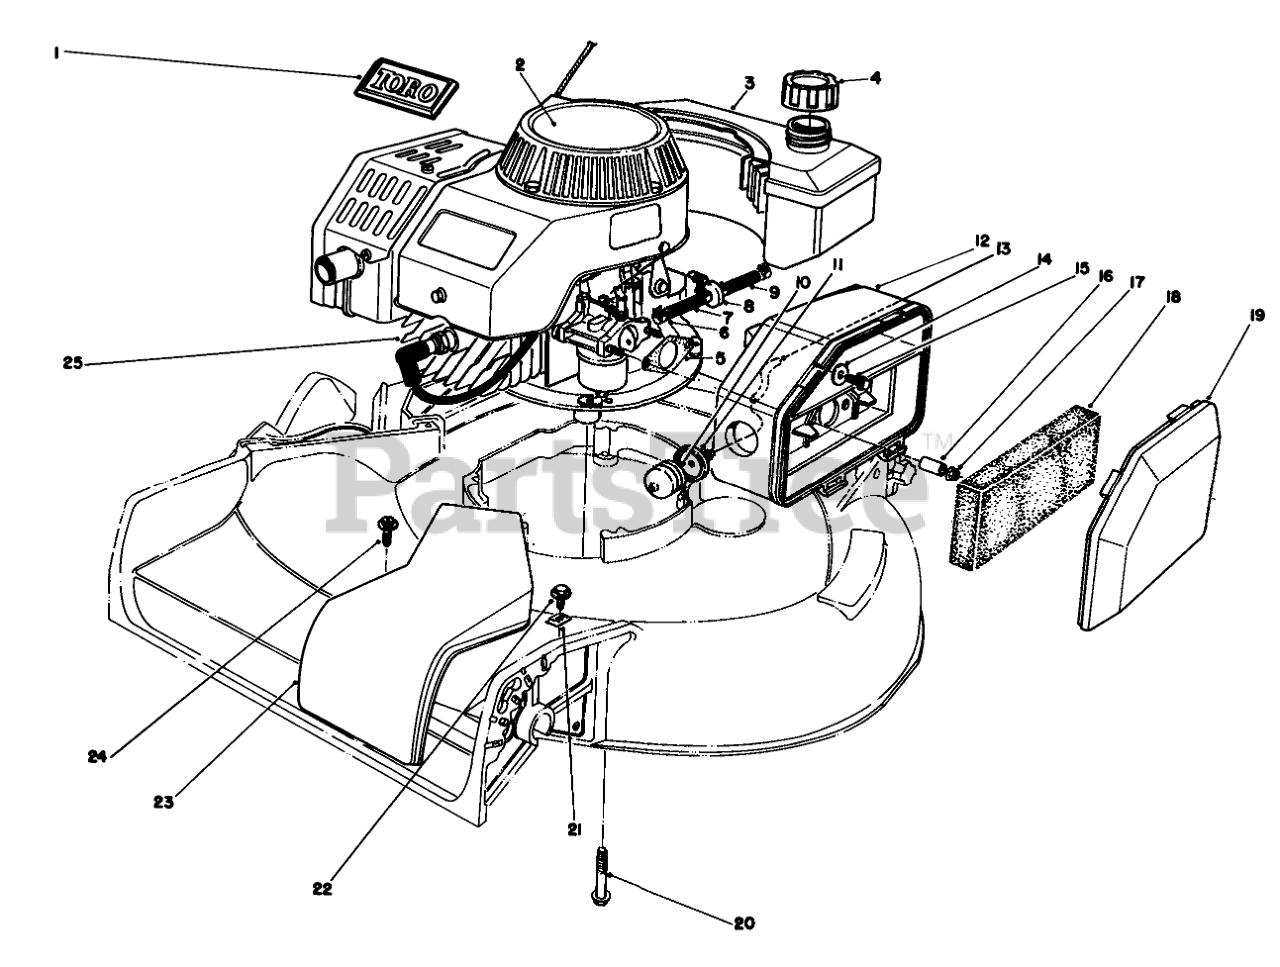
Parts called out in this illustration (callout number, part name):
1	TORO LOGO PLT
2	DECAL- 2 CYC RECOIL
3	FUEL TANK ASM
4	GAS CAP ASM
5	GASKET-AIR CLEANER
6	CLAMP-FUEL LINE
7	HOSE-FUEL
8	FILTER-FUEL
9	HOSE-FUEL
10	Bulb-Primer
11	BODY-PRIMER
12	BODY-AIR CLEANER
13	HOSE-PRIMER
14	WASHER-FLAT
15	SCREW-HH
16	SPACER
18	ELEMENT-AIR CLEANER
19	COVER-AIR CLEANER
20	SCREW-HHF, WHIZ
21	Cable Clamp
22	SCREW-HWHTF
23	Cow-Belt
24	SCREW
25	Engine (Complete)
